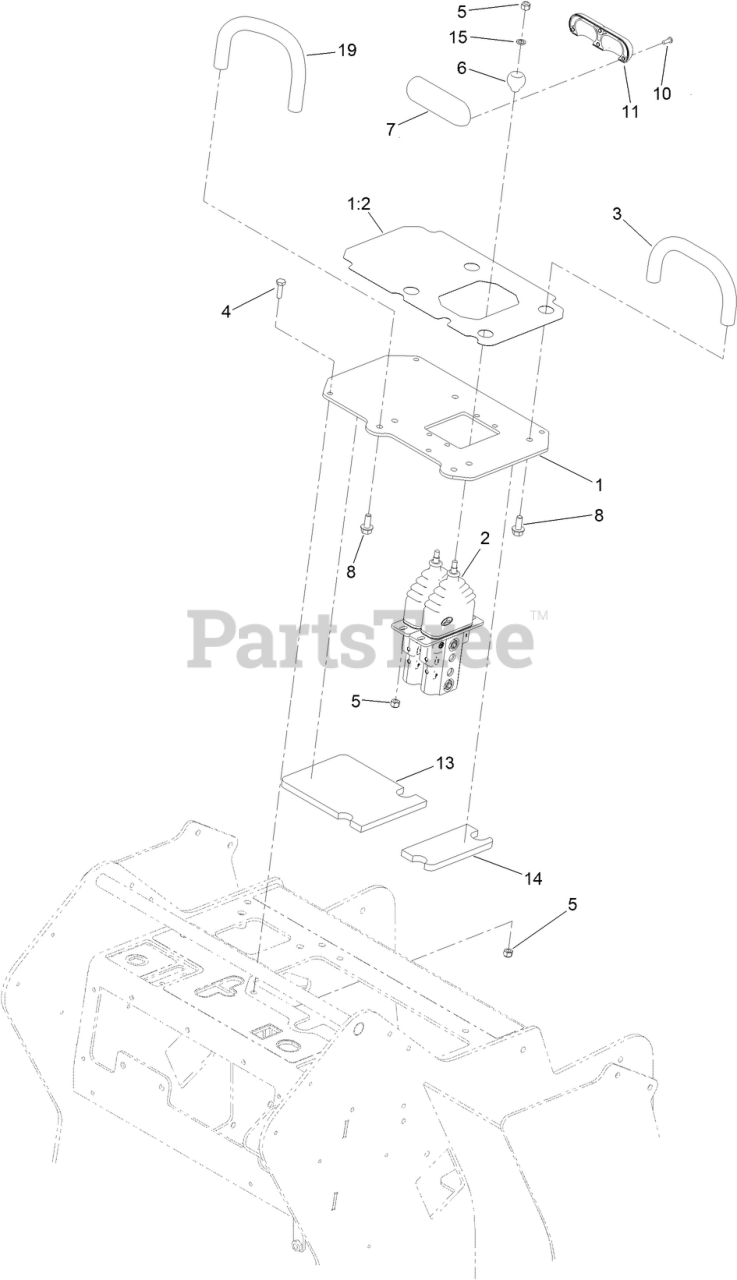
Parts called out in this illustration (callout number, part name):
1	PLATE-CONTROL
1:2	DECAL-CONTROL PANEL
2	VALVE-CONTROL (TRACTION)
3	BAR-REFERENCE
4	SCREW-HH
5	NUT-LOCK, NI
6	BALL-TRACTION
7	HANDLE-CONTROL
8	SCREW-HHF
10	SCREW
11	HANDLE-TRACTION
13	FOAM-SHIELD, HEAT
14	FOAM-SHIELD, HEAT
15	SPACER-BEARING
19	BAR-REFERENCE
